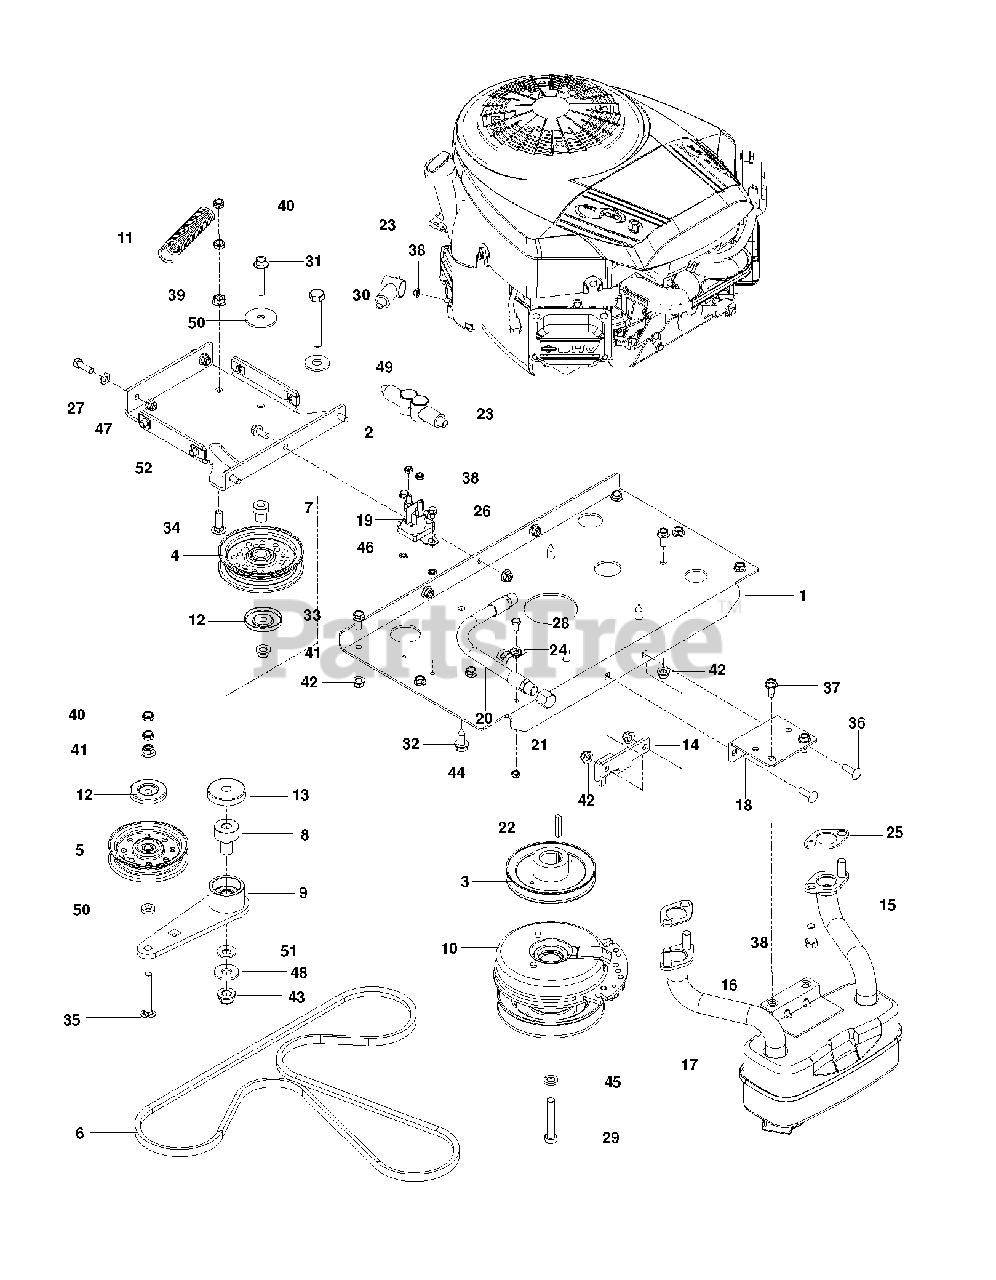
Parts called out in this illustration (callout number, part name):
1	PLATE, ENGINE W/DECALS
2	PLATE, IDLER, BLK
3	PULLEY, V, 1.125 BORE
4	IDLER PULLEY
5	FLAT IDLER PULLEY
6	BELT, HYDRO, 3400
7	PIVOT, IDLER
8	PIVOT, BEARING
9	ARM, IDLER, STEEL, W/BGS
10	CLUTCH 200 FT LB
11	SPRING, PUMP
12	DUST SHIELD
13	SHIELD, DUST
14	STOP, CLUTCH, BLACK
15	RP.EXHAUST.TUBE.LH.BS/TWIN
16	EXHAUST.TUBE.RH.BS/TWIN
17	MUFFLER ASM TWIN
18	BRKT, MUFFLER, BLK
20	OIL DRAIN HOSE
22	KEY, 1/4 SQ X 1 1/4
25	SPRING.BYPASS.CRD
26	HWST 1/4C X 3/8
27	HCS 5/16C X 1
28	HCS 1/4-20.
29	BOLT 7/16F X 2 1/2
30	HCS 1/2C X 3 1/4
31	HHFS 3/8-16 X 2.0 GD 5
32	HHFS 3/8-16 X 1.0 THD FORMING
33	HHFS 5/16-18 X 3/4
34	RHSNB 3/8-16 X 1-1/4
35	RHSNB 3/8-16 X 2.75
36	RHSSNB 5/16C X 1.0
37	BOLT 5/16-18 X 3/4
38	SCREW.SOCKET.HEAD.5/16-18
39	JAM NUT 1/4C (2 2 PW01)
40	NUT HEX 3/8-16 NYLON, THIN
41	NUT 3/8-16 HEX FLG NYLOC ZD
42	5/16-18 NYLOC FLANGE NUT
43	NUT, 1/2-13 HEX FLG NYLOC ZD
44	NUT 3/8C WHIZ
45	WASHER 7/16 LOCK
46	WASHER 1/4 INT TOOTH
47	FLAT WASHER 5/16 SAE
48	WASH USS FLAT 1/2
49	WASHER 3/8 X 3/4 X .187 TK
50	WASHER, 3/8 SPEC
51	CONTACT BELLSPR 1/2
52	U-CLIP 5/16-18 NUT RETAINER
